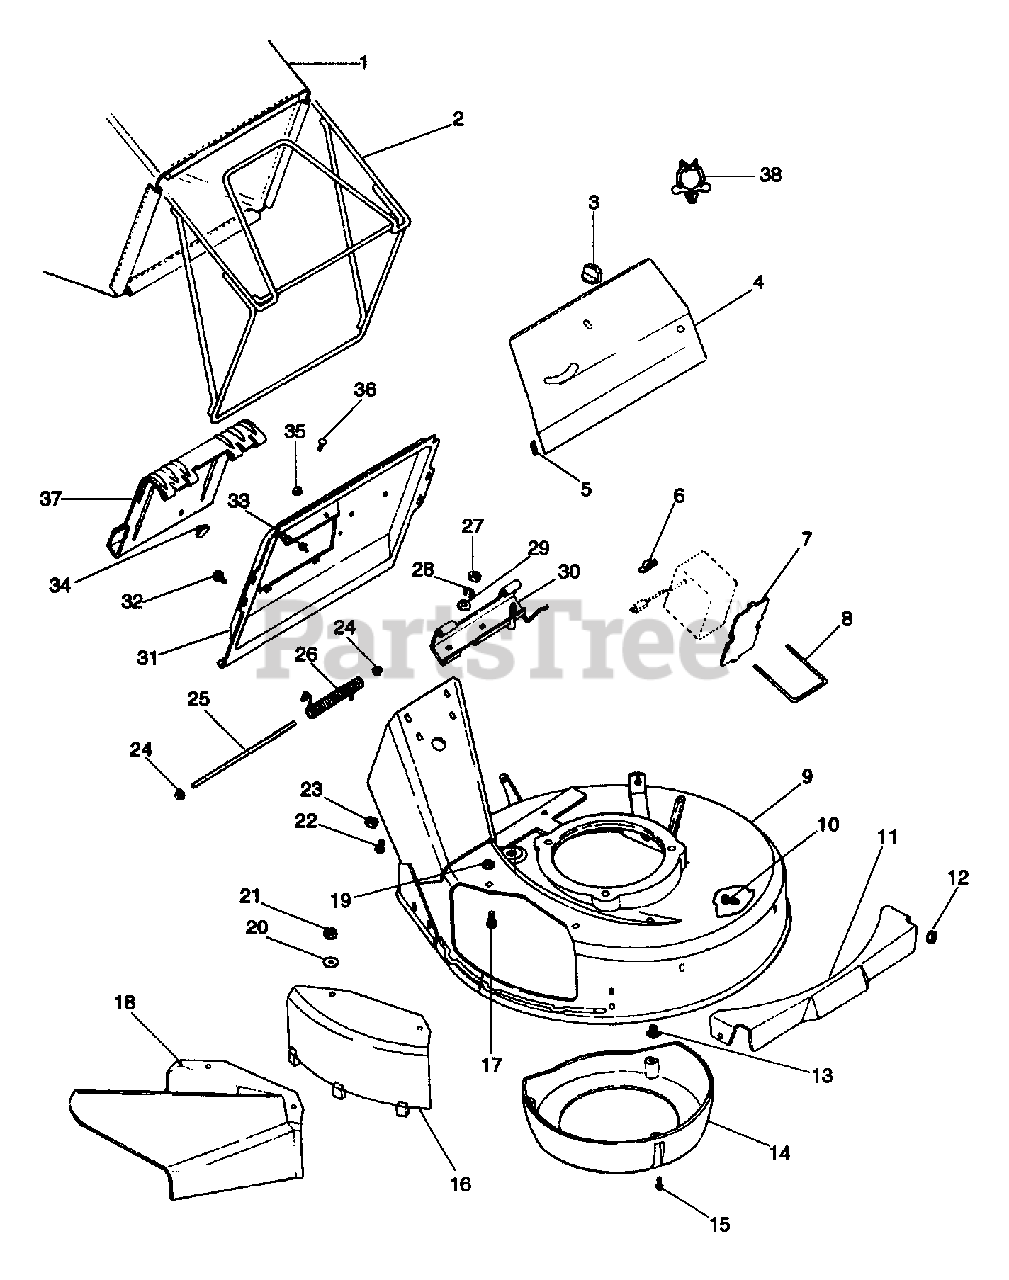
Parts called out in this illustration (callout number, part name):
1	BAG,CONSUMER BLACK 15 OZ/YD2
1	BAG,COMMERCIAL WHITE
2	BAGGER FRAME
3	WING - NUT
4	DRIVE COVER
5	TRIM BUMPER
6	NUT-WING 8-32
7	HOLD DOWN PLATE
8	U-BOLT
9	MOWER PAN W/DECALS PUSH
9	MOWER PAN W/DECALS SP/COMM
9	MOWER PAN W/DECALS BBC
10	BLT-RDHDSQSHNK .31-18X.50 YZ
11	FRONT PANEL
12	NUT-LK .312-18 GR A PL
13	PLASTIC GROMMET
14	CENTER BAFFLE
15	SCR-TAP 10-16X.62 SLPH PL AB
16	SIDE DISCHARGE COVER
17	BLT-RDHDSQNK .31-18X.75 SHT PL
18	DISCHARGE CHUTE
19	NUT-PUSH .312
20	WSHR-FL-STL .38X.875X.083 PL
21	NUT-LK-NYL.312-18 PL
22	BLT-RDHDSQNK .25-20X.62 PL
23	NUT-LK-FLG .250-20 PL
24	PUSH NUT, .25
25	DOOR PIN
26	SG-TORS .120X.68X3.09
27	NUT-HEX .250-20 PL
28	WSHR-LK .250X.077 HVY PL
29	WSHR-FL-STL .380X.875X.179 PL
30	HINGE BASE
30	HINGE BASE WELDMENT
31	CATCHER PLATE
32	SCR-TAP 12-24X.50 HWH PL TR
33	SCR-TAP 10-24X.375 TORX PHD
34	BUTTON BUMPER
36	@BLT-RHDSSQNK .25-20X.38 G2YZ
37	CATCHER PLATE DOOR
38	SNAP-IN CLIP
